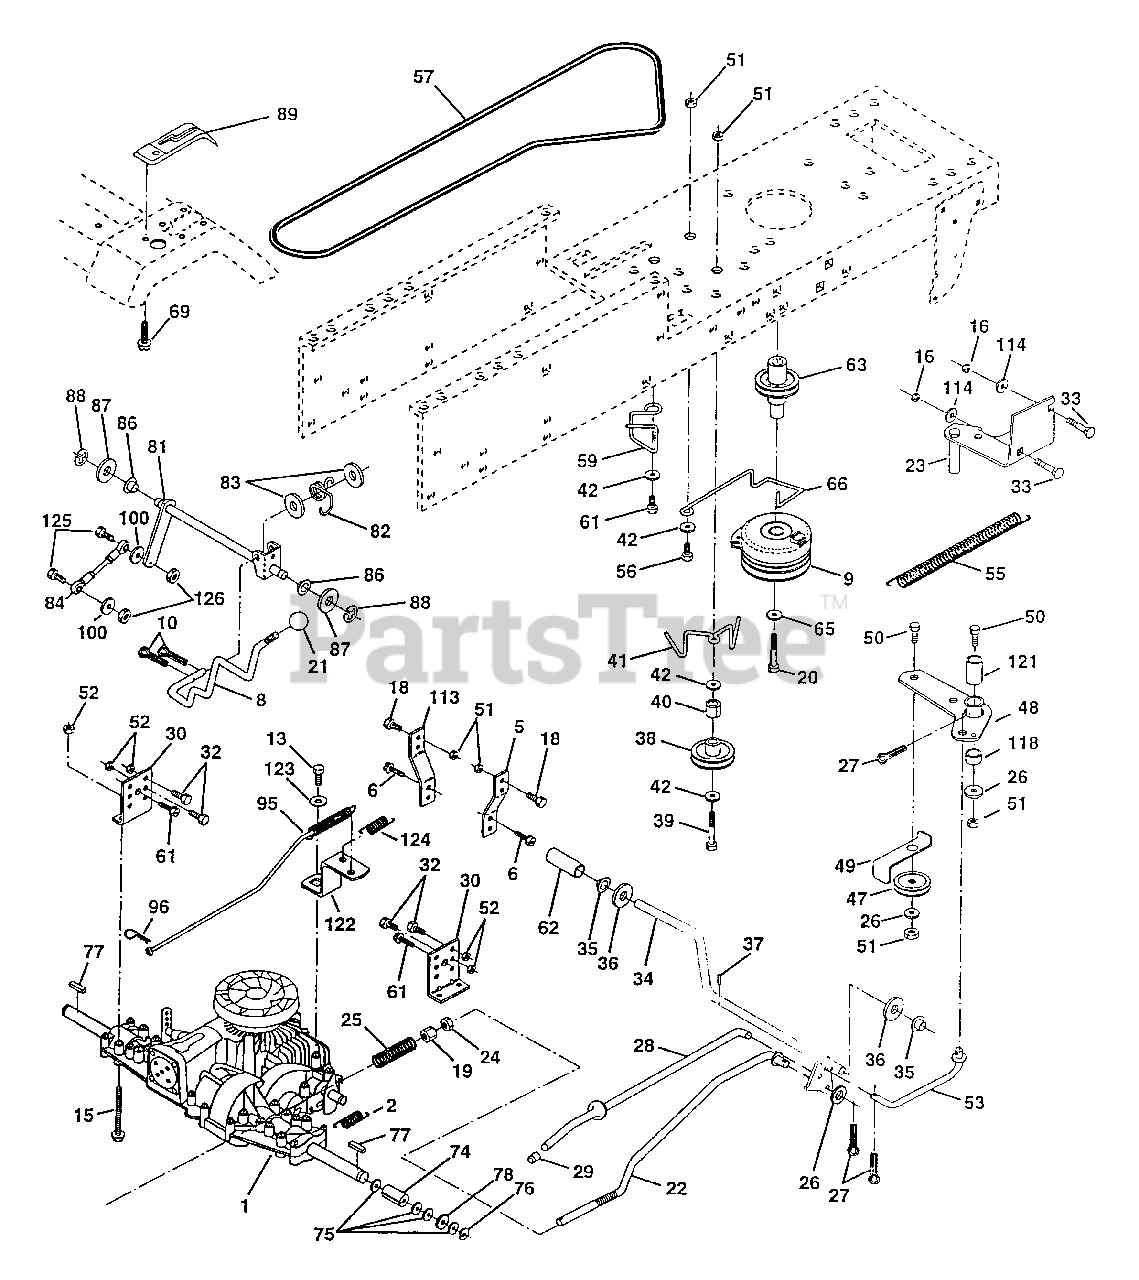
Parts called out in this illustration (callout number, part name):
1	Transaxle
2	Spring, Return, Brake
5	Strap Torque R
6	Screw Thdrol 5/16-18 x 3/4
8	Rod Shift Fender STLT
9	Clutch Elecric
10	Pin Cotter 1/8 x 1 CAD
13	Bolt 1/4-28 Unf Gr. 8 w/Patch
15	Bolt Hex 5/16-18 Unc Flghd
16	Nut Lock Hex W/Ins. 5/16-18 Unc P
18	Bolt Fin Hex 3/8-16 Unc x 1 Gr.5
19	Nut Lock Hex W/Ins 3/8-16 Unc
20	Bolt, Hex 7/16-20 x 4-1/4 Ga. 5
21	Knob, Duckhead 1/2-13 Unc Blk
22	Rod, Brake
23	Bracket Asm Mtg CL
24	Nut Hex Jam 3/8-16 UNC
25	Spring, Brake Rod
26	Washer
27	Pin Cotter 1/8 x 3/4 CAD.
28	Rod, Parking Brake
29	Cap,Parking Brake
30	Bracket, Transaxle
32	Bolt Hex Hd 5/16-18 Unc x 3/4
33	Bolt Carriage 5/16-18 UNC x 3/4
34	Shaft, Foot Pedal
35	Bearing, Nylon
36	Washer
37	Pin, Roll (AYP part number)
38	Pulley, Idler, Flat
39	Bolt
40	Spacer Split
41	Keeper, Belt Idler
42	Washer 13/32 x 13/16 x 12 Ga
47	Pulley, Idler, V-Groove Plastic (AYP part number)
48	Bellcrank Assembly
49	Retainer, Belt Style Spring
50	Bolt (AYP part number)
51	Nut
52	Nut Crown Lock 5/16-18
53	Link, Clutch
55	Spring, Return, Clutch
56	Bolt, Fin Hex 3/8-16 UNC x 1 1/4
57	V-Belt, Ground Drive
59	Keeper, Center Span (AYP part number)
61	Screw Thdrol. 3/8-16 x 3/4 Ty. TT
62	Cover, Pedal
63	Pulley Clutch Electric EVX
65	Washer Lock Hvy HLCL Spr 7/16
66	Keeper Belt Engine
69	Screw Hex Wsh Hi-Lo 1/4-1/2 unc
74	Spacer, Axle
75	Washer 25/32 x 1-1/4 x 16 Ga.
76	E-Ring
77	Key, Square
78	Washer 25/32 x 1-5/8 x 16 Ga
81	Shaft Asm. Cross
82	Spring Torsion T/A
83	Washer 17/32 x 3/4 x 16 Ga.
84	Rod, Tie PVST 18"
86	Bushing Rod Strig. 629/632 ID
87	Washer 21/32 x 1-1/4 x 16 Ga.
88	Ring Klip #5304-62
89	Console, Hydro Shift STLT
95	Rod Asm. Bypass Hydro
96	Retainer Spring 1" Zinc/Cad
100	Washer 11/32 x 3/4 x 16 Ga.
113	Strap Torque Lh
114	Washer 11/32 x 3/4 x 14 Ga.
118	Spacer Bellcrank
121	Nyliner Clutching STL
122	Plate Bypass PVST
123	Washer 9/32 x 5/8 x 16 Ga.
124	Spring Return PVST
125	Bolt Fin Hex 5/16-18 Unc x 1.00
126	Nut Lock 5/16-18 Nc Thd (AYP part number)
